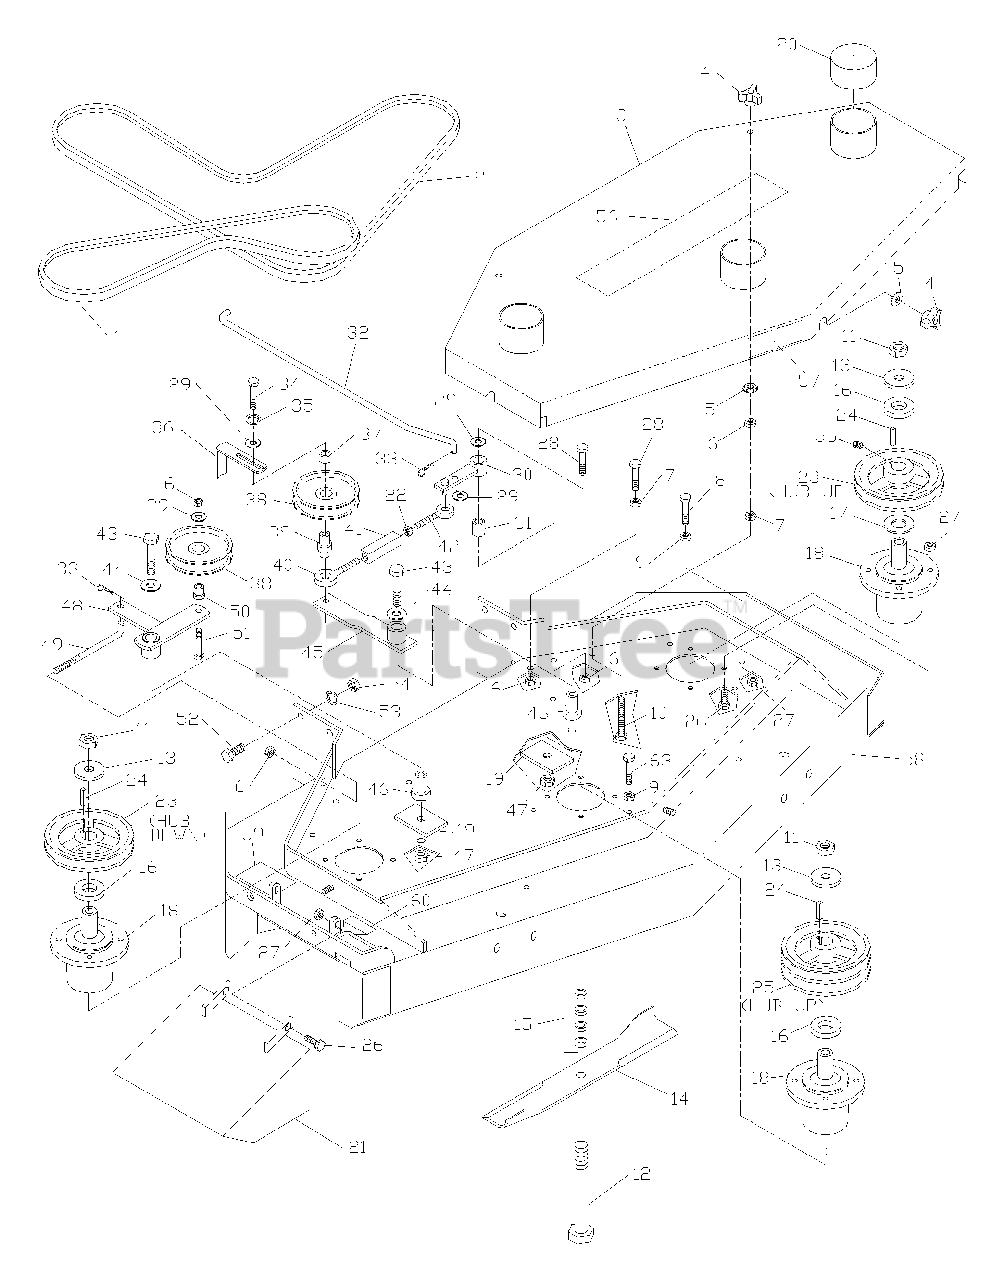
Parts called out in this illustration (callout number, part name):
1	AUX. BLADE BELT
2	BLADE BELT 48
3	48" BELT SHIELD
4	THREE PRONG KNOB
5	3/8 SEALING WASHER
8	HCS 5/16CX3 (BELT GUIDE)
9	HFLN 5/16C
10	TAPBOLT-3/8C X 4 1/2
12	HCS 5/8F X 8 1/2
12	HCS 5/8F X 9 (CENTER)
13	SUPPORT WASHER
14	BLADE 16 1/4
15	BLADE SPACERS
17	MACH. BUSHING 10 GA.
18	HOUSING ASM.
21	DEFLECTOR CHUTE
22	5/16C HEX NUT
23	PULLEY W/ SETSCREWS
24	1/4SQ. KEY X 1 1/8
25	DOUBLE PULLEY W/SETS.
26	HCS 5/16C X 1
28	HCS 3/8C X 2 1/4
29	FW 3/8 STD
30	ENGAGEMENT ARM
31	SLEEVE BUSHING
32	BLADE ROD 48"
33	#2 HAIRPIN
34	HCS 3/8C X 2 1/2
35	3/8 LOCK WASHER
38	IDLER PULLEY
39	EYEBOLT PIVOT
40	LEFT HAND EYEBOLT
41	TURNBUCKLE
42	RH. EYEBOLT
43	HCS 1/2C X 2 3/4
44	1/2 FLAT WASHER
46	IDLER SPINDLE
47	1/2C NYLOC NUT
48	AUX. IDLER ARM
49	TENSION ROD
50	IDLER FLANGE BUSHING
51	HCS 3/8C X 1 3/4
52	HCS 7/16C X 1 1/2
53	7/16 LOCK WASHER
54	7/16C HEX NUT
55	5/16 NYLOC SETSCREW
56	DECAL, HUSQVARNA
57	DECAL, NASCAR
58	48 DECK W/DECALS
59	DECAL, DANGER
60	DECAL, CPSC
63	HCS 5/16C X 4
